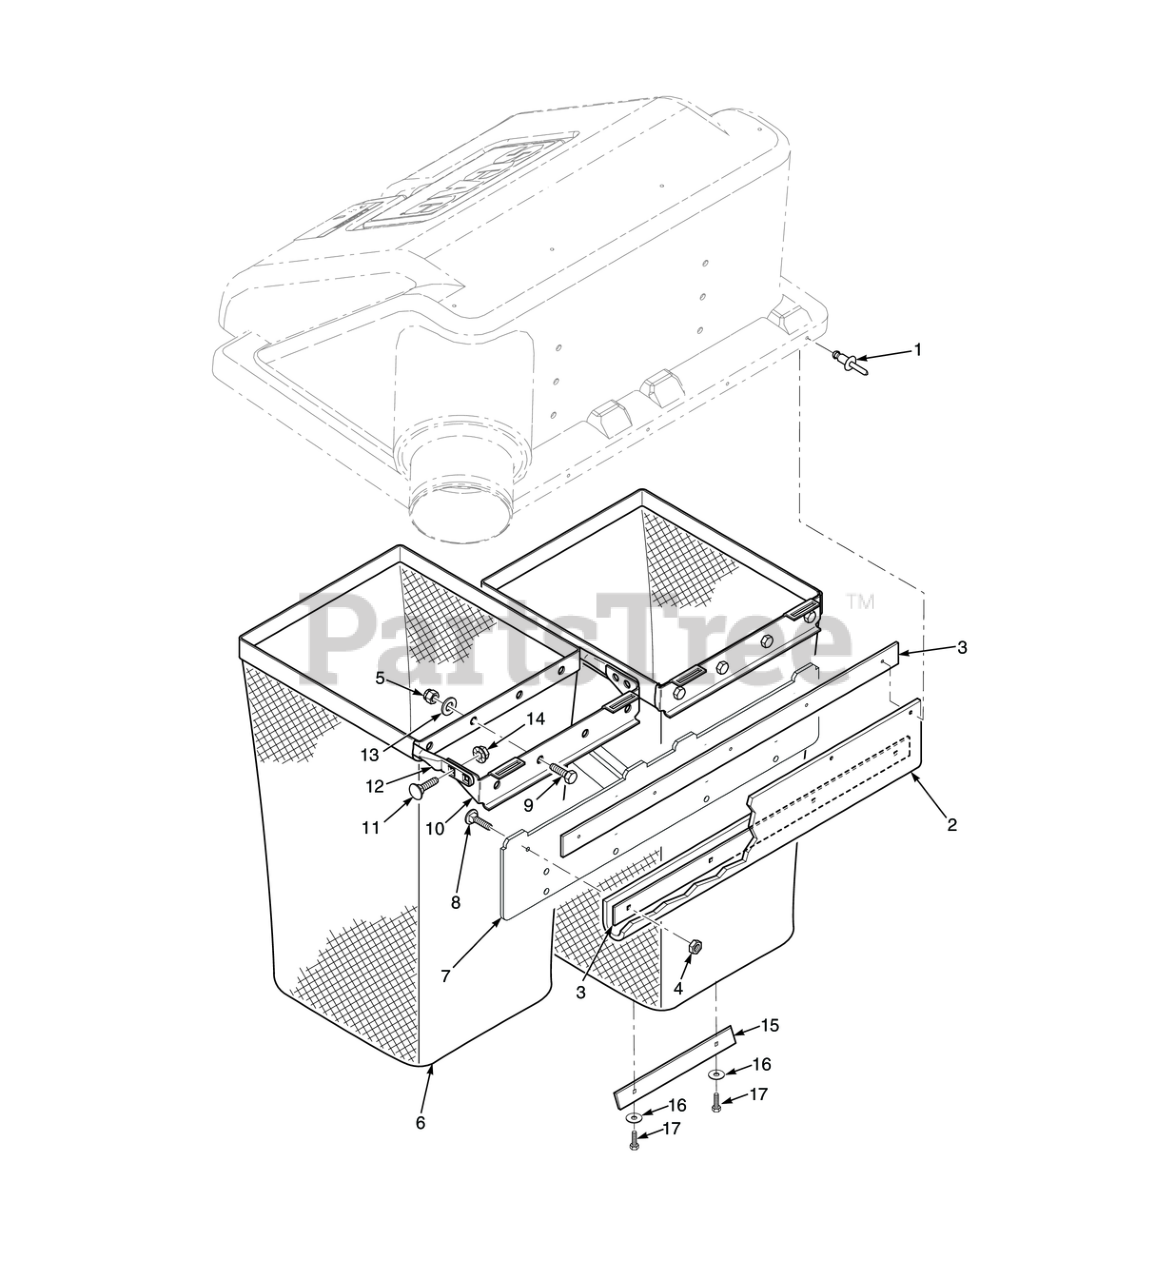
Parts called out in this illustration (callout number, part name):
1	Pop Rivet, 3/16 x .652"
2	Diode (part of wire harness)
3	Retainer, Seal
4	Bolt, Hex Hd. 1/2-13 x 9-1/2"
5	HEX NUT, ELASTIC STOP LOCK, 5/16-18
6	Bag Assembly
7	Frame Weldment, Bag Support
8	BOLT, HEX HEAD, 1/4-20 X 3/4 GR.5
9	BOLT, SERRATED FLANGE HEX HEAD 5/16-18 X 3/4"
10	Mount, Bag Frame Tube
11	Bolt, 5/16-18 x .75 RHSN Carriage
12	Tube, Bag Support
13	Flatwasher, 5/16-.375 x .875 x .083 (35BV & 37BV-EFI)
14	Nut, Serrated Flange 5/16-18 (Right Front Engine Mounting, Briggs and Kohler Only)
15	Handle
16	Flatwasher, 3/8-.406 x 1-1-1/2 x 7 Gauge
17	Bolt, 5/16 - 18 x 1 - 1/4" Hex Head
